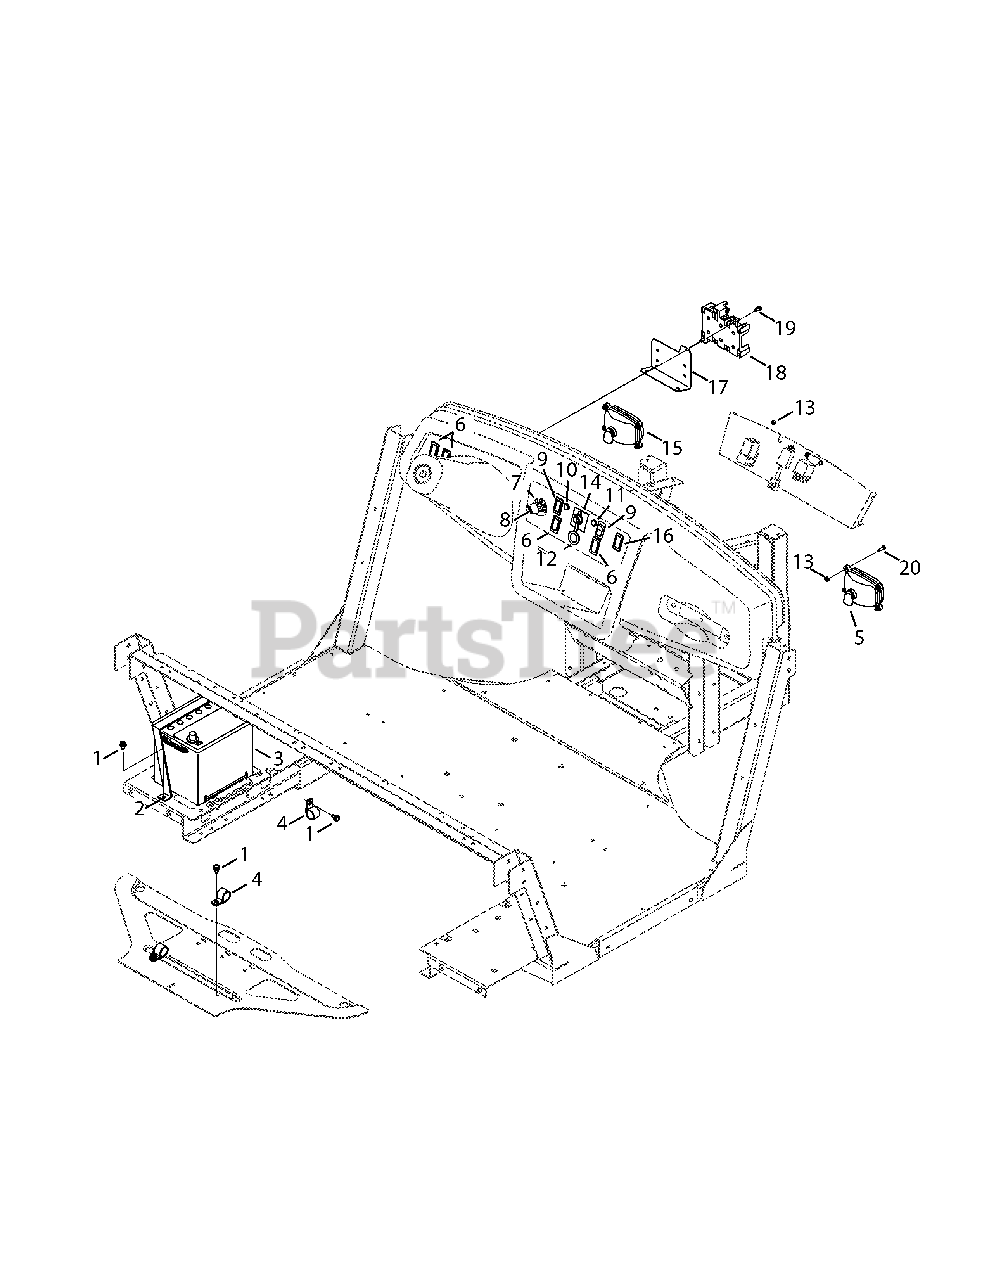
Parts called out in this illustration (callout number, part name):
1	Screw, TT, 5/16-18 x .500
2	Bracket, Mt., Battery
3	Battery, 450 CCA Wet
5	Head lamp Bulb
6	Panel, Plug, Switch
7	Switch, Key, 4 Pos. Delta
8	Key, Delta, Plastic
9	Switch, 4x4, Rocker
10	Lamp, Ind., Green, Incandescent
11	Lamp, Ind., Red, Incandescent
12	Receptacle, Power, 12v
13	Nut, Hex Lock, #10-24
14	Meter, Ind., Hour Flat Face
15	Headlight Assembly (Incl. # 21)
16	Seat Belt Indicator
17	Bracket, Fuse Mount
18	Relay, Holder, 3-Way
19	Screw, TT, 1/4-20 x .500
20	Screw, TT, #10-24 x .750
